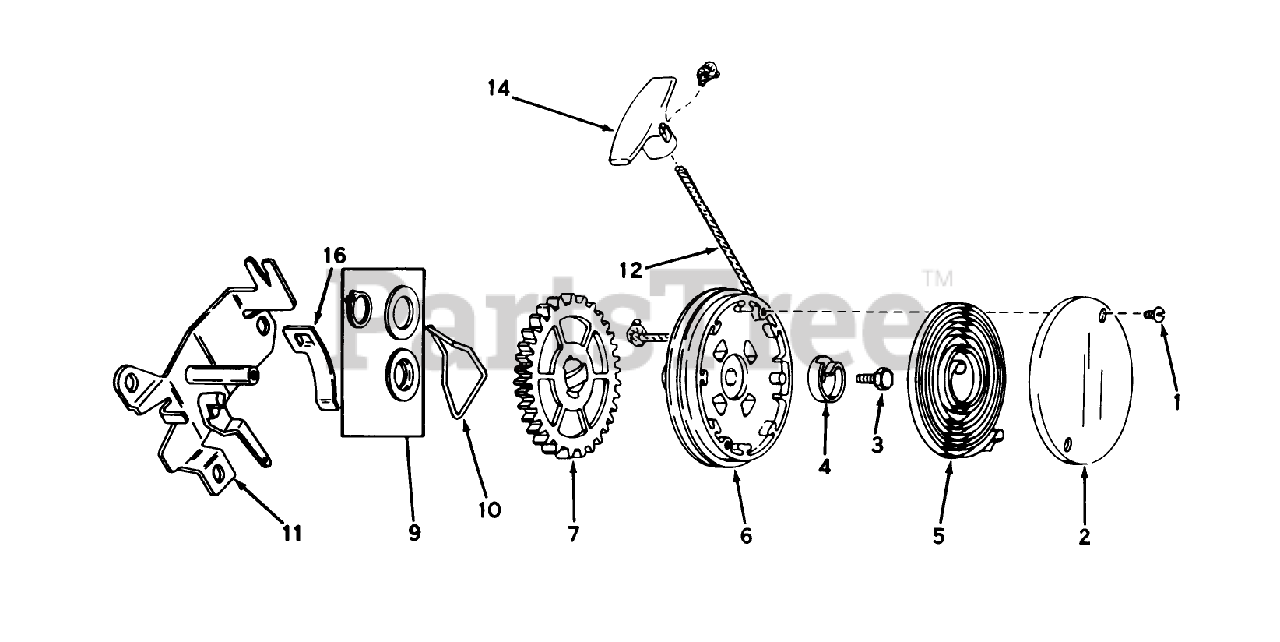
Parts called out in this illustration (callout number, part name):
1	Screw
2	Cover, Spring
3	Screw, Hex Washer Head
4	Hub Spring
5	Spring, Rewind
6	Pulley Assy. (Incl. No. 9)
9	Kit, Thrust Wash. Snap Rg.
10	Brake
11	Bracket Assy., Mounting
12	Rope-Starter
14	Handle-Starter
16	Clip Rope
